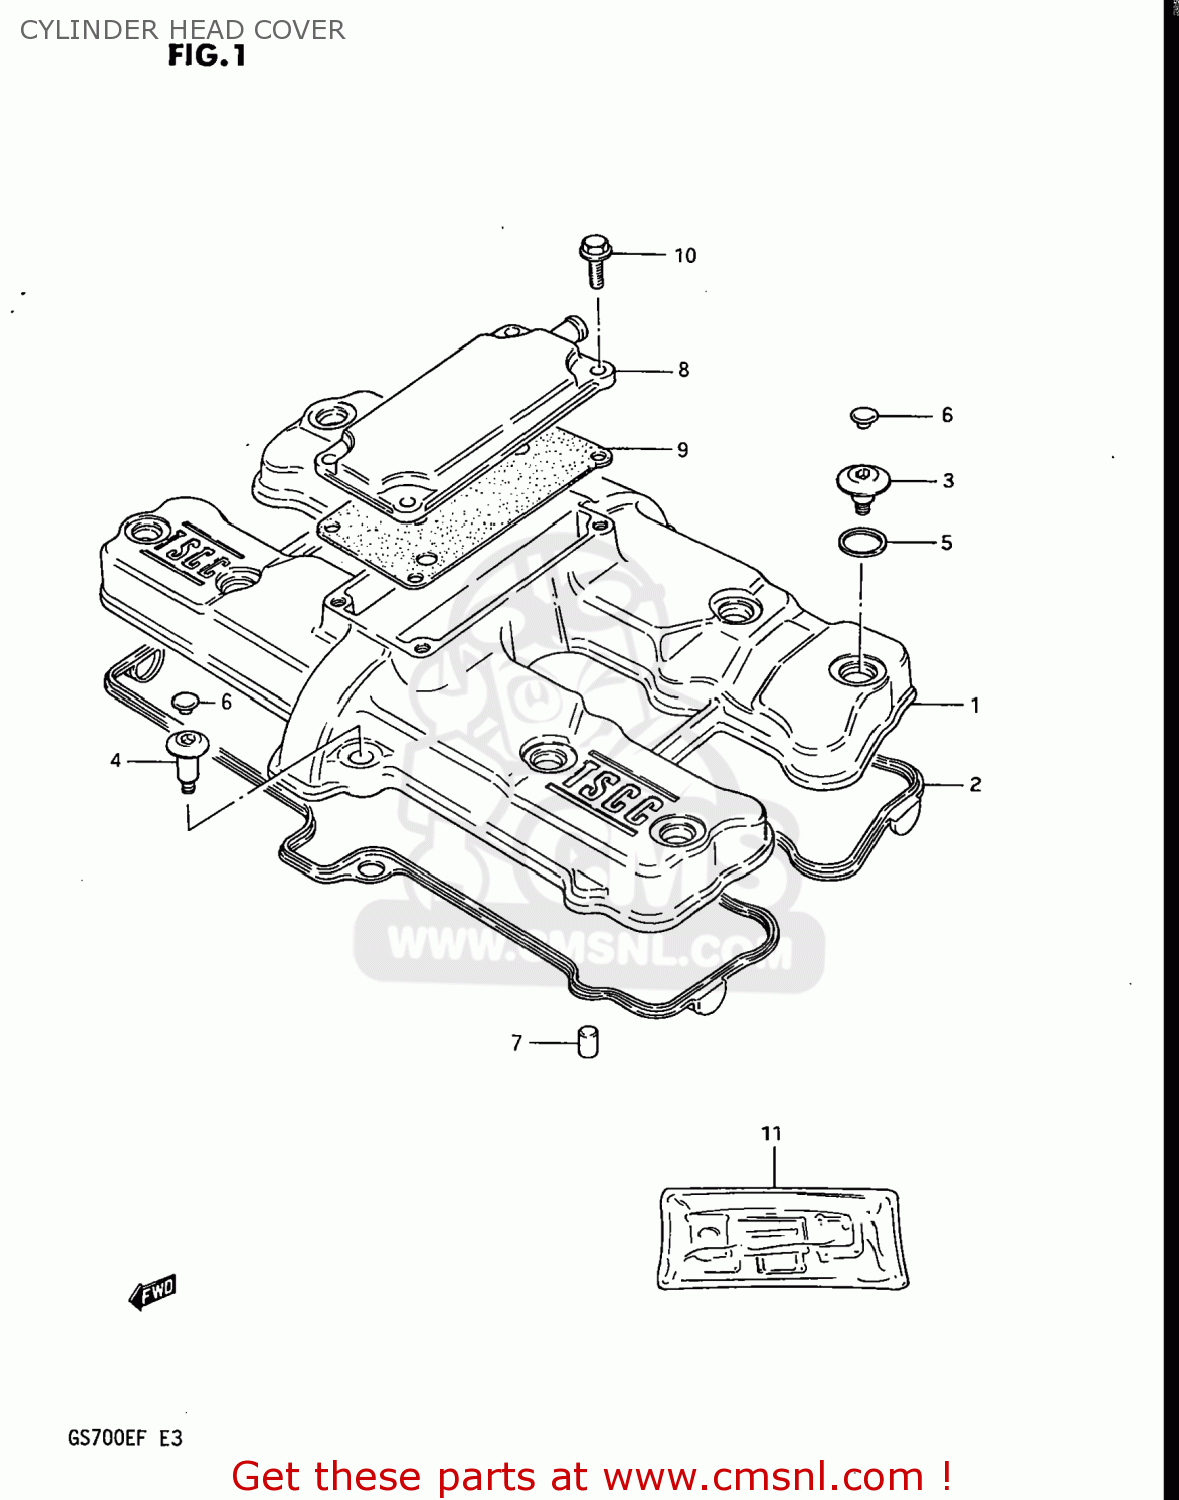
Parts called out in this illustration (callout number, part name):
1	COVER,CYLINDER HEAD
2	GASKET,HEAD COVER (NAS)
3	BOLT(7X5.5)
4	BOLT(7X19)
5	WASHER
6	CAP(OD:10)
7	PIN
8	COVER,BREATHER
9	GASKET (MCA)
10	BOLT,REAR
11	GASKET SET
